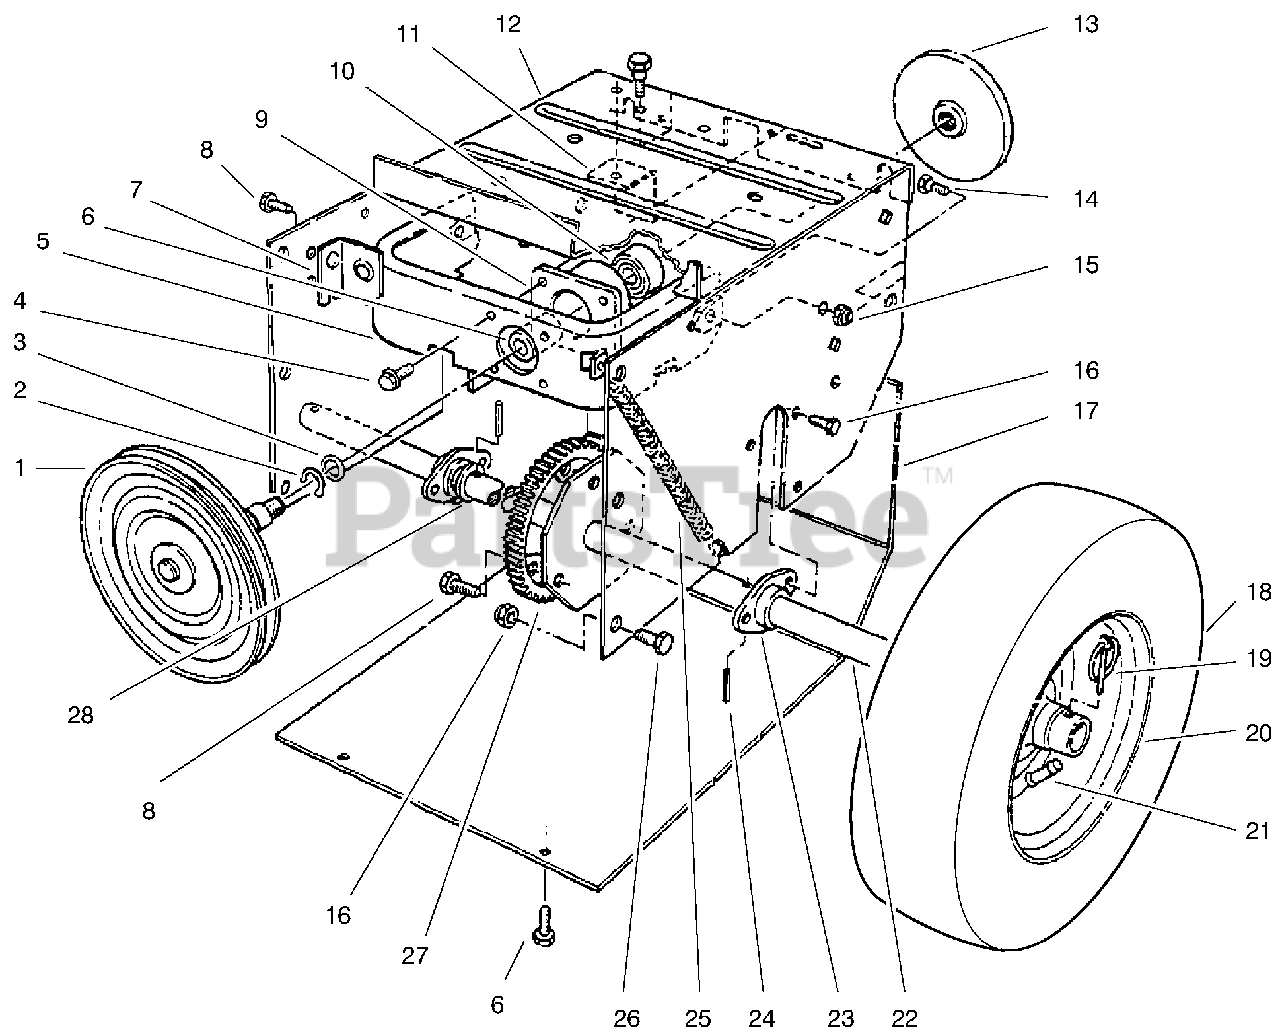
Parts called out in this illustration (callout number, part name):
1	Pulley & Shaft
2	Ring-Snap
3	Washer-Thrust
4	Screw-Tapping
5	Frame-Friction Plate
7	Mount-Clutch Rod Front
8	Screw-Self Tap. Hex. Hd.
9	Hub-Frame
11	Mount-Clutch Rod Rear
12	Frame-Traction
13	Plate-Friction
14	Bolt-Shoulder
15	Nut-Lock
16	Screw-Self Tap. Hex. Hd.
17	Cover-Bottom
19	Pin-Klik
22	Shaft-Axle
23	Bearing-Axle
25	Spring-Friction Plate
26	Screw-Hex. Hd.
27	Gear-Axle
28	Washer-Thrust
